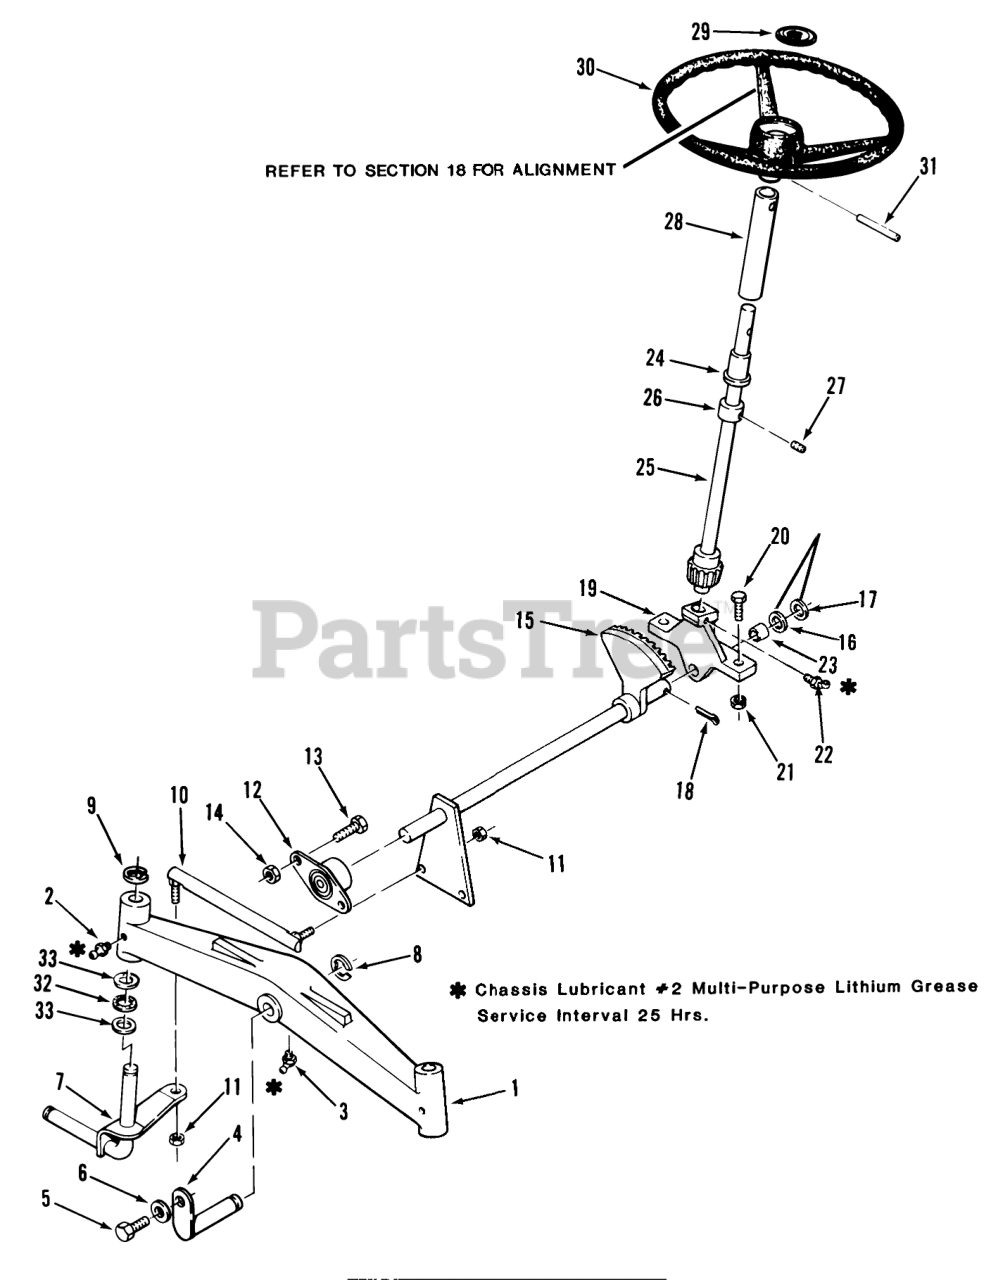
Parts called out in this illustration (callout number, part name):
1	Front Axle
2	Zerk
3	FITTING-GREASE
4	Pin and Plate
5	SCREW
6	Lockwasher
7	Front Spindle RH
7	ASSY LH SPINDLE & R
8	E-RING
9	E RING
10	Tie Rod RH
10	Tie Rod LH
11	NUT-6
12	BEARING-FLANGED
13	Bolt
14	Nut
15	ASSY STG SHAFT LOWER
16	WASHER-SHIM
17	WASHER
18	PIN-4
19	Support
20	Bolt
21	Nut
22	FITTING-GREASE
23	BEARING-BRONZE
24	BEARING
25	ASSY UPPER STG SHAFT
26	Collar
27	SCREW-SET
28	Collar
29	STEERING WHEEL INSE
30	Steering Wheel
31	PIN-ROLL, SPIROL
32	BEARING-THRUST
33	WASHER-THRUST
